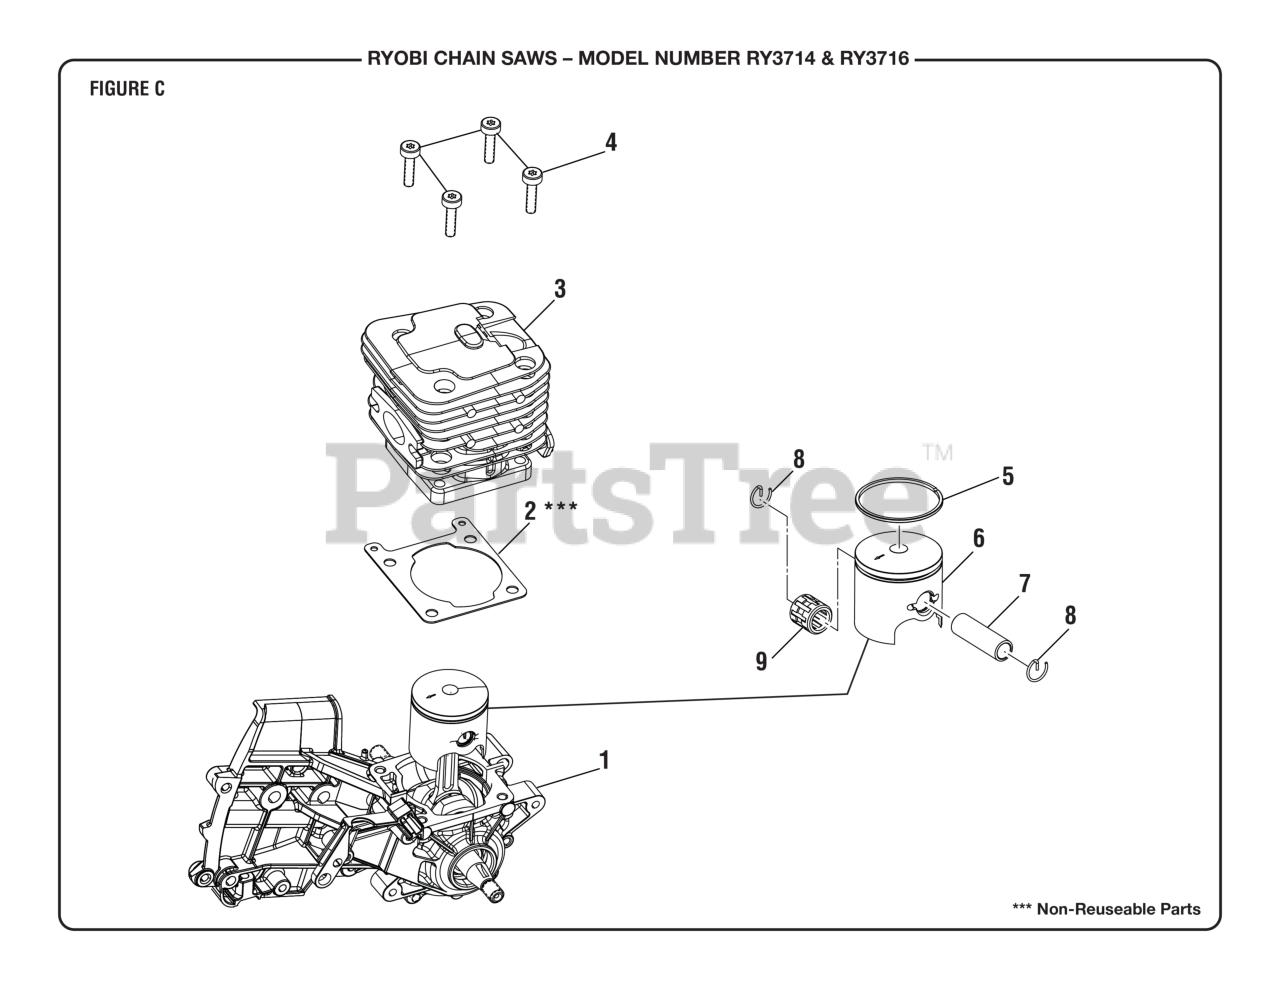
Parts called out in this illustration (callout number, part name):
1	Crankcase & Crankshaft Assembly
2	Crankcase Gasket
4	Cap Screw (M5 x 20 mm, T25 Torx Soc. Hd.)
5	Piston Ring
7	Piston Pin
8	Piston Pin Clip
9	Needle Bearing
